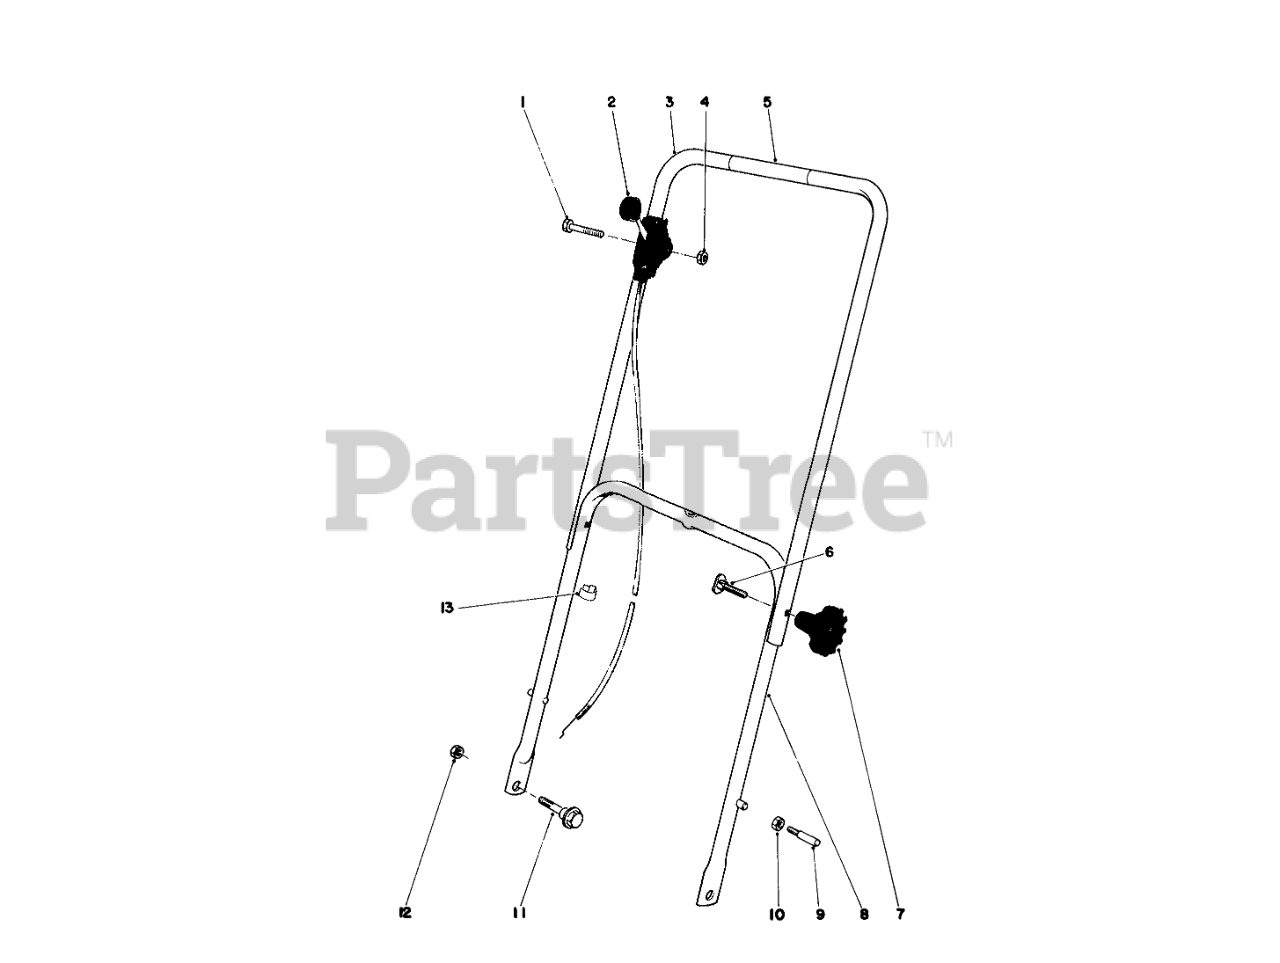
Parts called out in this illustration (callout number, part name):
1	SCREW-HH
2	Throttle Control
3	Upper Handle
4	NUT-LOCK
5	Danger-Decal
6	HANDLE SCREW
8	19 LOWER HANDLE ASM
9	HANDLE PIN
10	Nut
11	SCREW-SHOULDER
12	Nut
